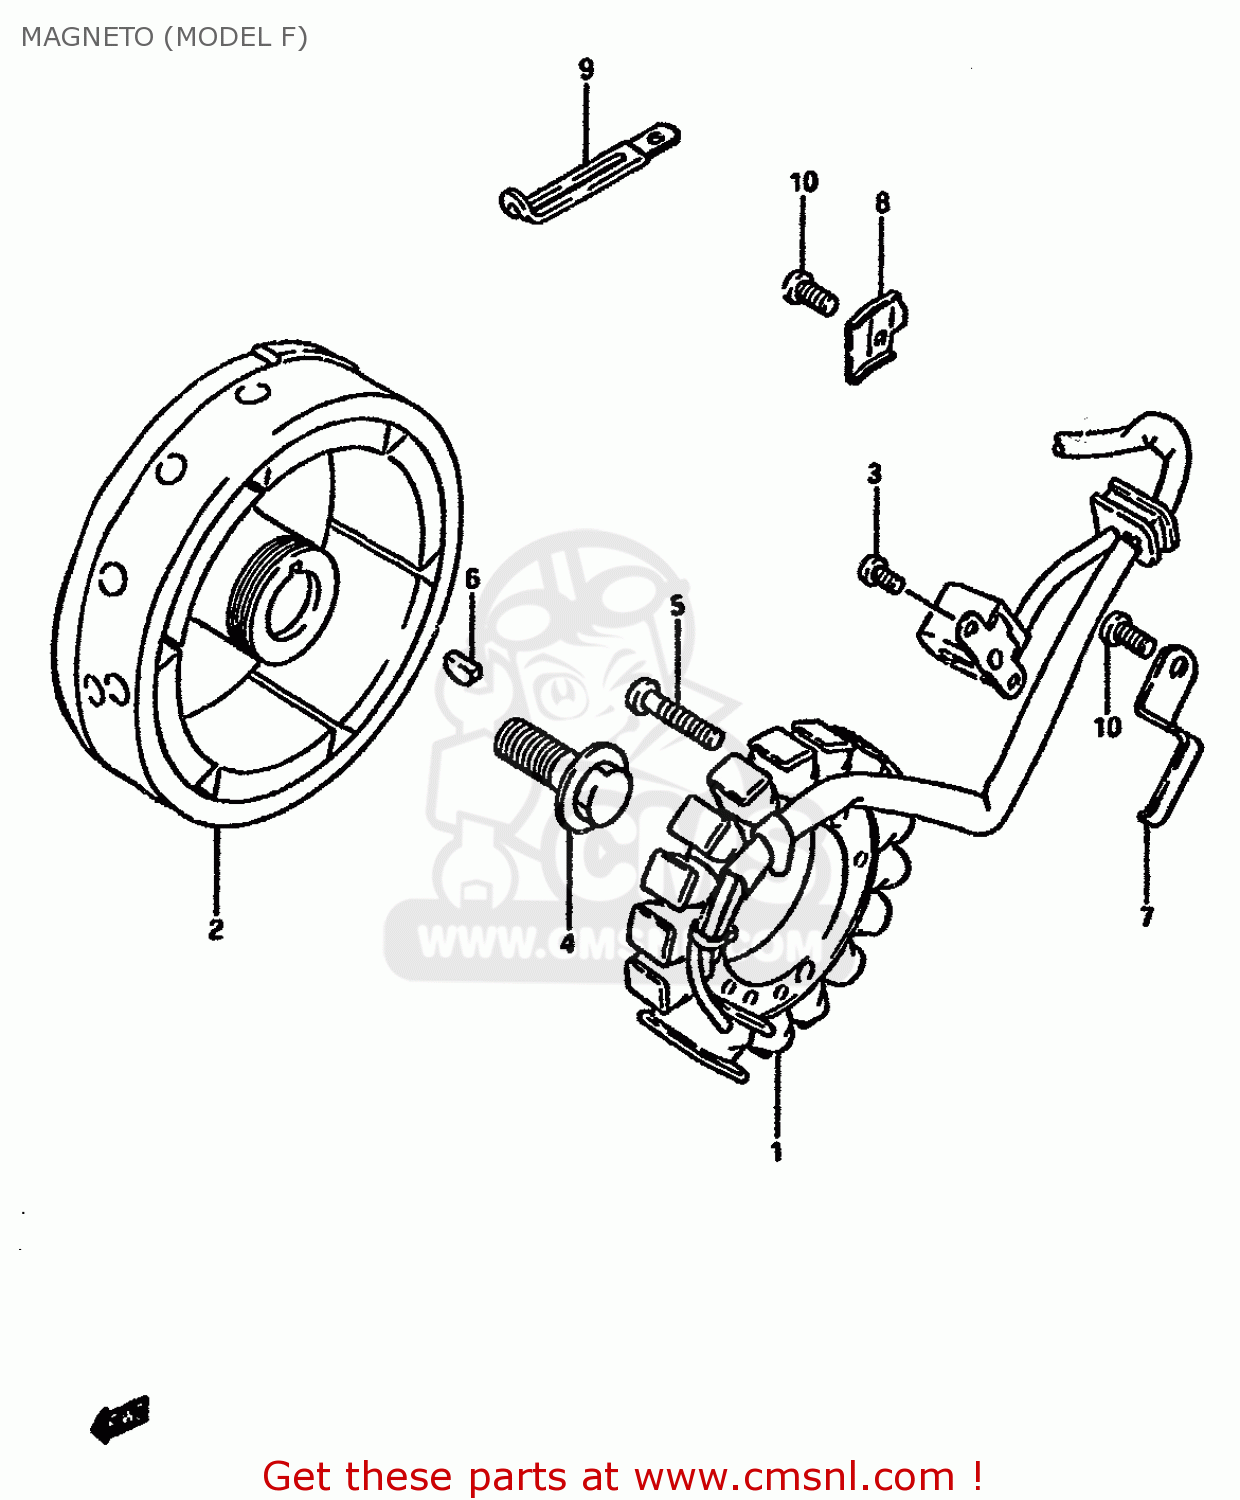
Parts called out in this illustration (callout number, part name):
1	STARTER ASSY
2	ROTOR,FLYWHEEL
3	SCREW 5X12
4	BOLT(14X43)
5	SCREW,6X30
6	KEY 4MM
7	CLAMP,MAGNETO LEAD WIRE
8	CLAMP,MAGNETO LEAD WIRE
9	CLAMP
10	SCREW
